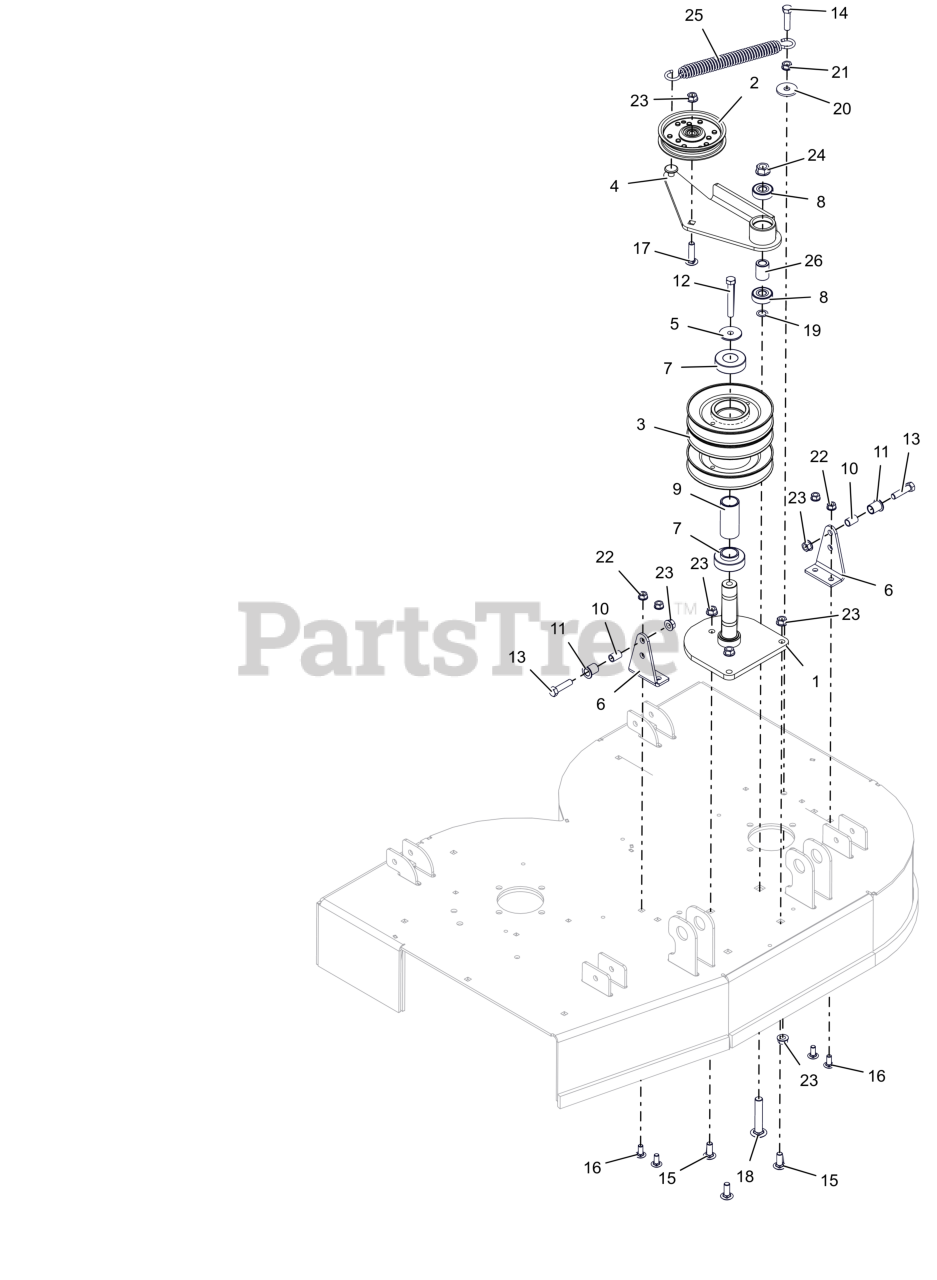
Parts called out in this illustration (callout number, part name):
1	WLDMT, JACKSHAFT BASE (BLACK)
2	ASM, 4" IDLER (.75 WIDE)
3	WLDMT, JACKSHAFT HOUSING
4	WLDMT, DECK IDLER ARM
5	RETAINER, JACKSHAFT SPINDLE
6	BRKT, IDLER PIVOT (BLACK)
7	BEARING- RG 1.00X2.0467X.591
8	BRG-BALL .500X1.38X.437
9	SPCR, SLV 1.010 X 1.250 X 2.661
10	SPCR, SLV .385 X .500 X .750
11	BSHG, FLANGE - .500X.625X.750X.062
12	BLT, HEX .38-16X2.75 G8 ZCC
13	BLT, HEX .38-16X1.50 G5 ZCC
14	BLT, HEX 0.375-16X1.5 GR8 ZCC
15	BLT,RHSSN .38-16X1.00 G5 ZCC
16	BLT, RHSSN.31-18X.750 G5 ZCC
17	BLT, RHSSN .38-16X1.50 G5 ZCC
18	BLT,RHSSN .500-13 X 2.75 G5 ZCC
19	WASHER, .500X.750X.020 THRUST
20	WSHR,FLT .406X1.375X.135 ZCC
21	NUT, SPNLK-FLG .38-16 G5 ZCC
22	NUT,LK-CTR-FLG .31-18 GF ZCC
23	NUT-LK-CTR-FLG .375-16 GF ZCC
24	NUT-LK-CTR-FLG .500-13 GG ZCC
25	SPRING- EXTENSION
26	SPACER .510 X .867 X 1.1485
